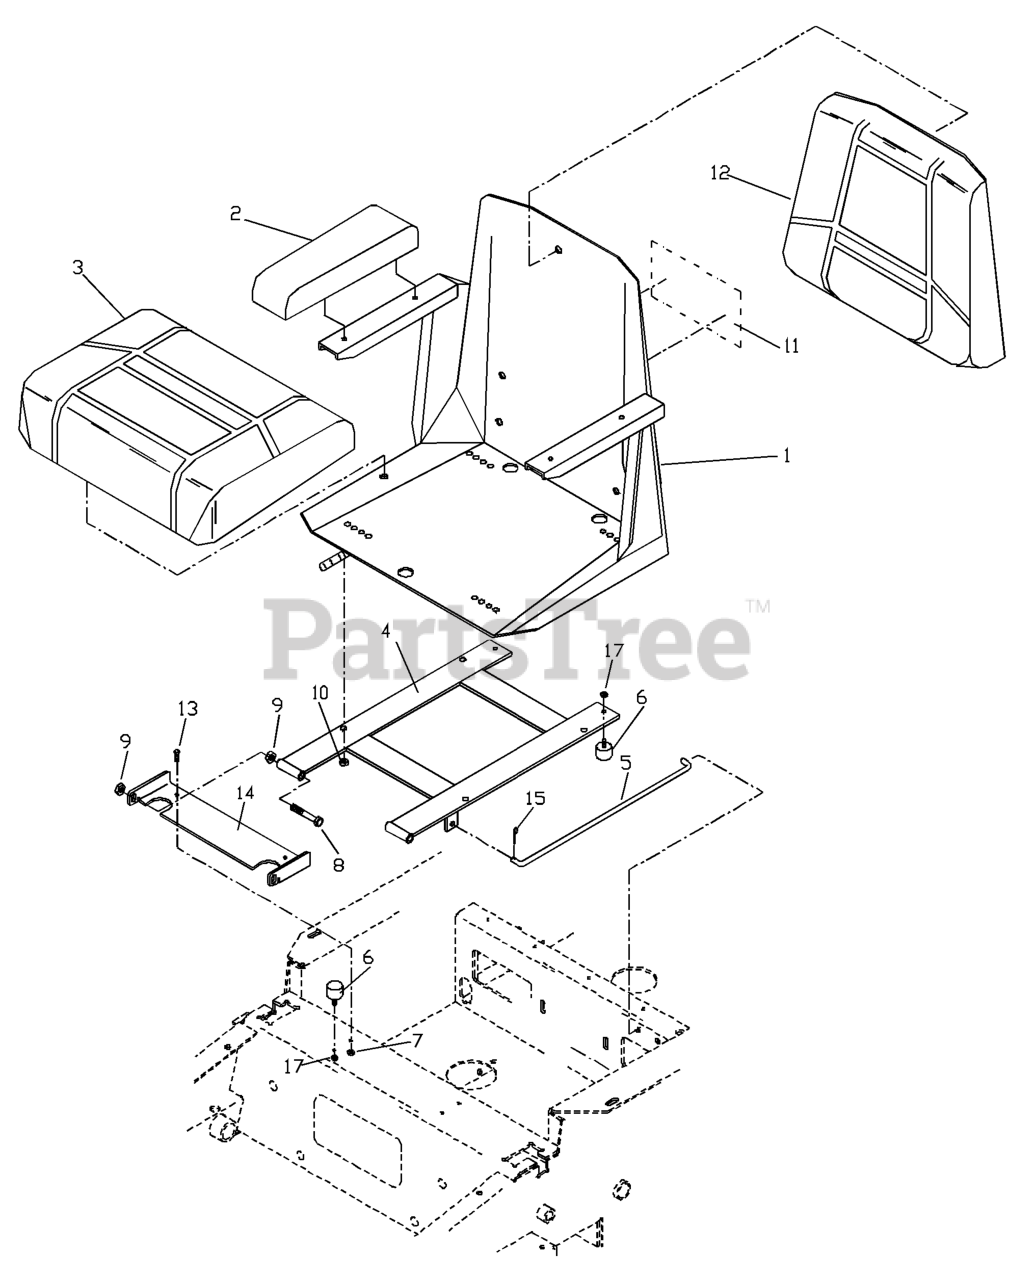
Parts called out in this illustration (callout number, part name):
1	SEAT COMPLETE
2	ARM REST CUSHION
3	SEAT CUSHION
4	SEAT MOUNT
6	STUD/PLATE MOUNT
7	NUT 1/4C CENTERLOCK
8	HCS 3/8C X 3
9	NUT 3/8C CENTERBLOCK
10	NUT M8-1.25HX NYL RNGGR8.8
11	DECAL, CROWN H
12	BACK CUSHION
13	HCS 1/4C X 3/4 HCS
14	SEAT BRKT W/DECAL
15	RP_COTTER PIN 1/8 X 3/4
16	SEAT RAILS
17	NUT.1/4-20.HEX.NYLOC.ZD
18	SEAT HARNESS
19	SEAT SWITCH
